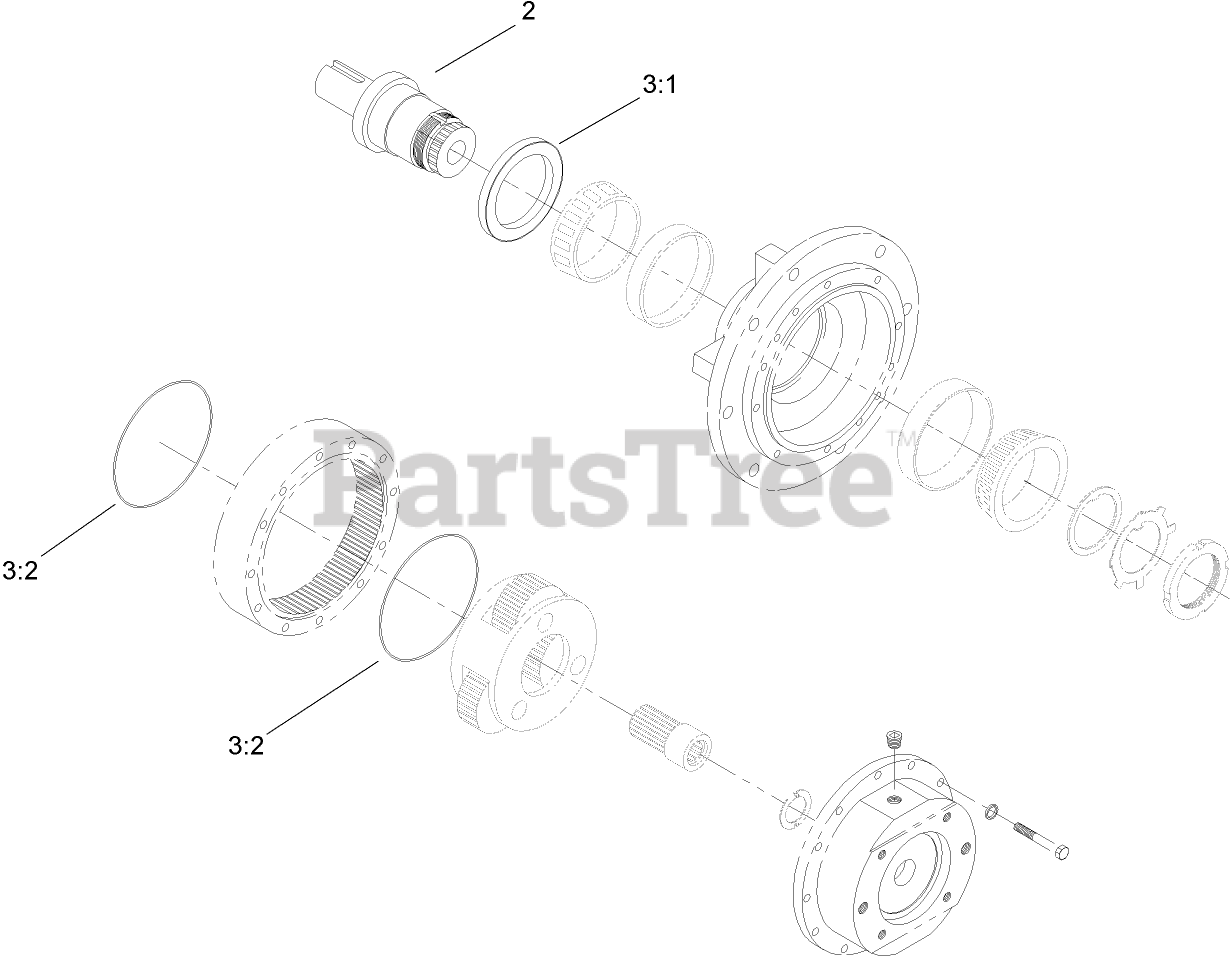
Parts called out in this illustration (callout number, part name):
2	SHAFT-OUTPUT
3	KIT-SEAL
3:1	Seal-Shaft
3:2	Seal-Dust
